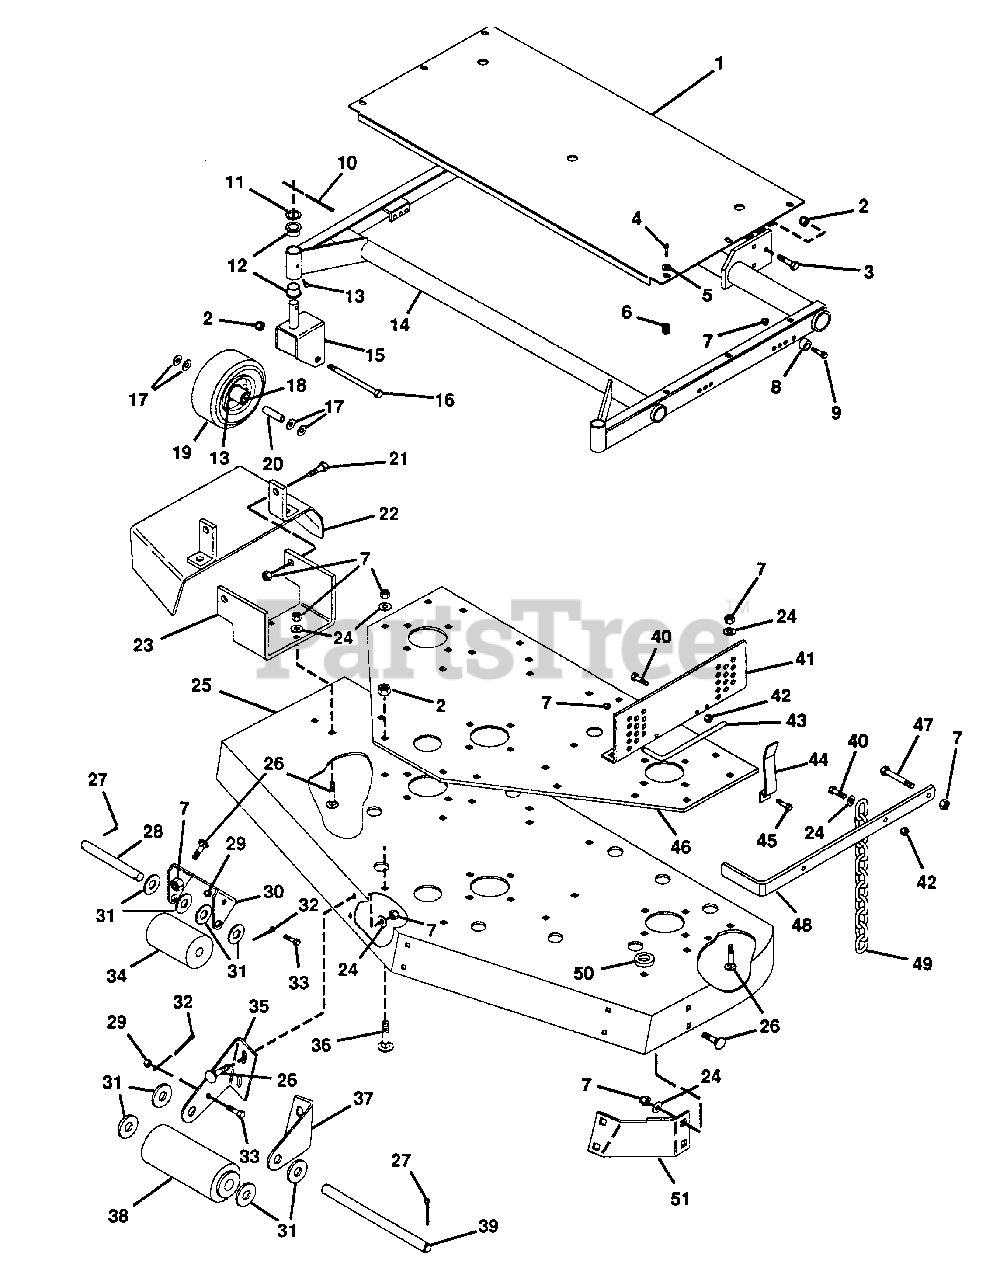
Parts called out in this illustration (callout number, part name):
1	CVR,BELT 60"PRO MWR
2	NUT-LK-NYL .50-13 YWZC
3	BLT-HEX .50-13X1.50 GR5 YWZC
4	SCR-TAP .25-20X.50 HWH TR YWZ
5	WSHR-FL-STL.281X.62X.065 YWZC
6	GRMT,PLASTIC
7	NUT-LK-NYL .38-16 YWZC
8	BUSH.,S.391X.621X.676 ST
9	BLT-HEX .38-16X1.50 GR5 YWZC
10	PIN-COTR .188X1.625
11	WSHR-HDND-THRUST 1.00X1.55X.03
12	BSHG-FLG1.020X1.385X.75X1.75NY
13	FTG,LUBE, .25-28 SELF THREAD
14	WLDMT,MOWER FRAME
15	WELDMENT, CASTER FORK (RED)
16	BLT-HEX .50-13X5.50 GR5YWZC
17	WSHR-FL-STL.50X1.25X.083 YWZC
18	BRG-BALL .752X1.50X.50
19	WHL 9X3.50
20	SPACER .532X.748X3.34
21	BLT-HEX .38-16X1.00 GR5 YWZC
22	WELDMENT, DISCHARGE CHUTE
23	BRKT,DISCHARGE
24	WSHR-FL-STL.406X.812X.065 YWZ
25	WLDMT,60"MOWER
26	BLT-RDHDSHSQNK.38-16X1.0 G5YZ
27	PIN-CTR .25X1.00 YWZC
28	ROD
29	NUT-HEX .25-20 YWZC
30	BRKT., ROLLER (RED)
31	WSHR-FL-STL.656X1.31X.095 YWZ
32	PIN-CTR .25X2.00 YWZC
33	BLT-HEX .25-20X.75 GR5 YWZC
34	RLR,GAGE
35	BRKT,ROLLER L.H.
36	BLT-RDHDSQNK .50-13X1.00 G5YZ
37	BRKT,ROLLER R.H.
38	RLR,GAGE
39	SHAFT,CENTER ROLLER
40	BLT-HEX .31-18X1.00 GR5 YWZC
41	BRKT,MOWER SUPPORT L.H.
41	BRKT,MOWER SUPPORT R.H.
42	NUT-LK-NYL .312-18 YWZC
43	PIN,MOWER LOCKING
44	SPRG,PIN
45	BLT-HEX .38-16X.75 GR5 YWZC
46	PLT,SUPPORT
47	BLT-HEX .38-16X2.0 GR5 FTD YWZ
48	BAR,LIFT
49	CHAIN,HEIGHTH ADJ
50	BUSHING .406 X .750 X .188
51	BFL,FRONT
